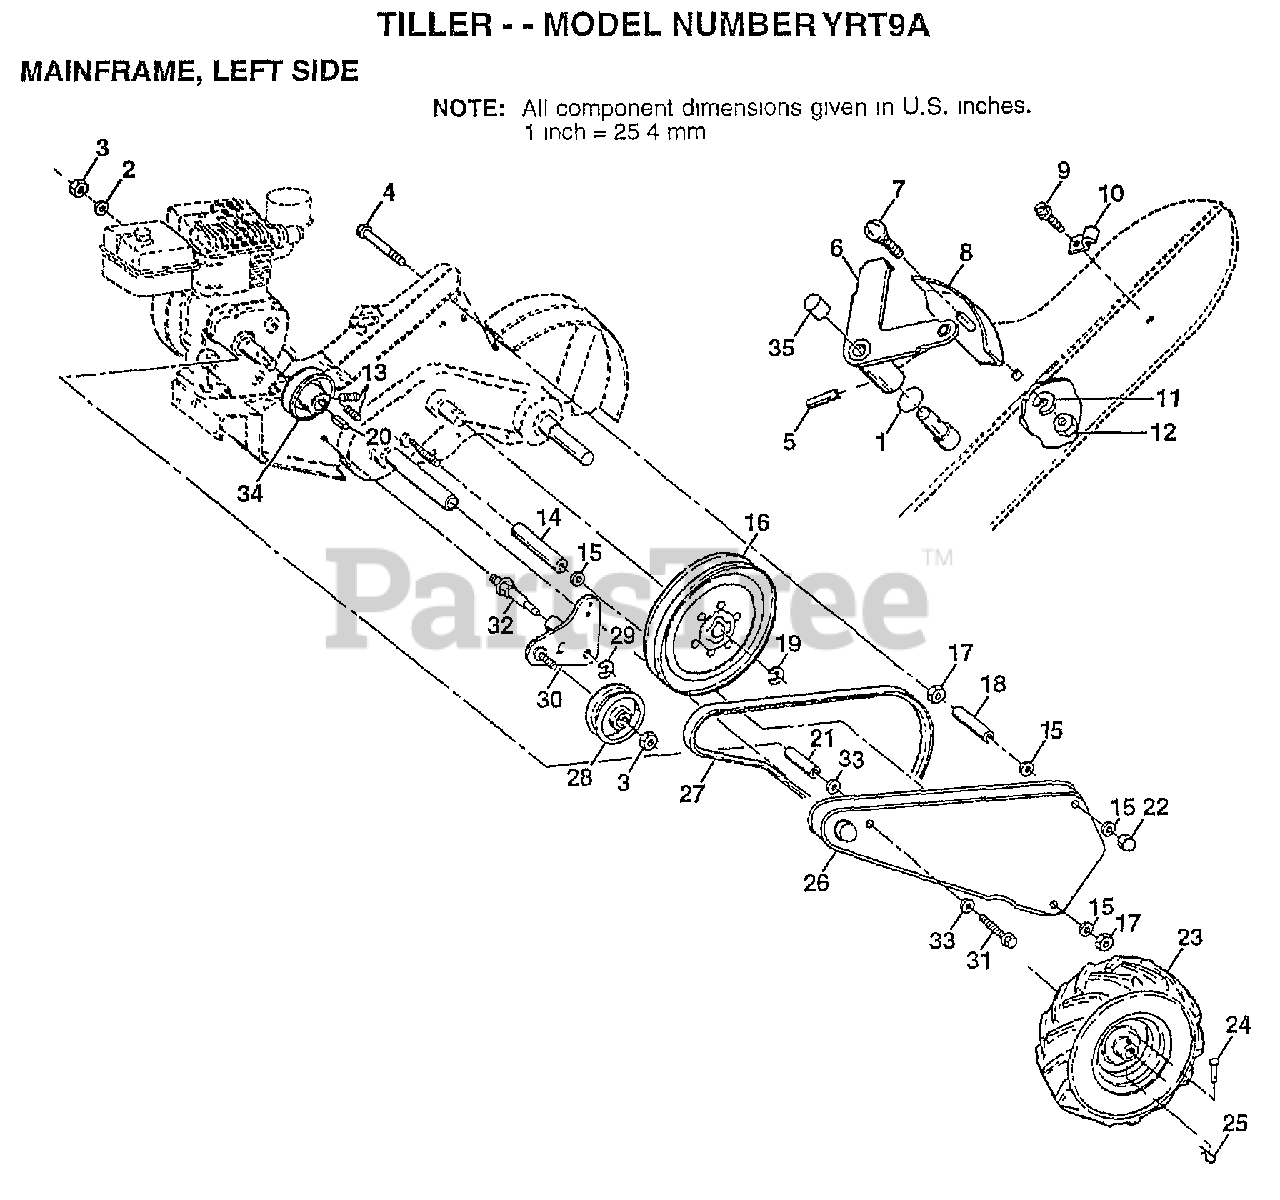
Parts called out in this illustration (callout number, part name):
1	O-RING TI
2	LOCKWASHER
3	NUT.HEX.3/8-16UNC
4	BOLT TI
6	LEVER ASM CRT
7	BOLT
8	PANEL TI
10	CONDIUT CLIP T
11	LOCKWASHER
13	SET SCREW
14	SPACER TI
15	WASHER
16	SHEAVE.TRANS.
17	NUT.HEX.5/16-18
18	SPACER TI
20	KEY TI
21	SPACER.SPLIT
22	NUT TI
23	TIRE TI
24	RIVET.PAN HD.1.75
25	SPRING.RETAINER
27	BELT.DRIVE
29	KLIP RING
31	BOLT1/2-20UNF2.75
32	SHAFT.IDLER
34	SHEAVE CRT
35	CAP PLUNGER BLACK
